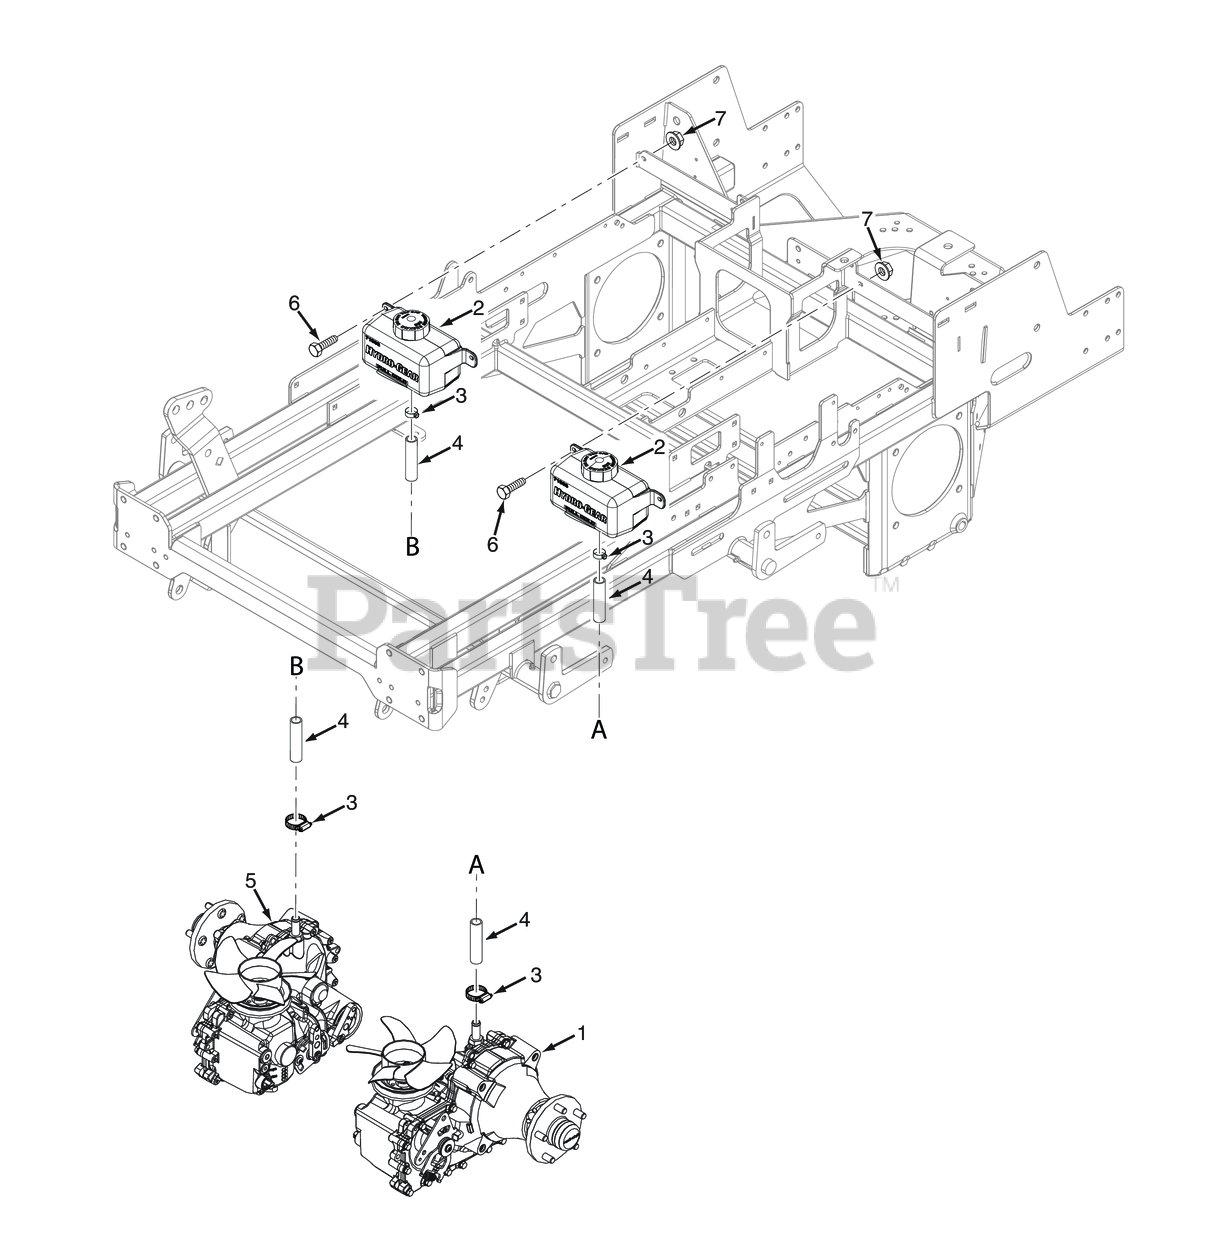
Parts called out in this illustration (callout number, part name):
1	Transaxle, LH
2	Hydraulic Tank, 1,000 ml
3	Clamp, 1" Max Dia.
4	HOSE 5/8 ID PUSH ON RUBBER CVD
5	Transaxle, RH
6	BOLT, HEX HEAD, 1/4-20 X 3/4 GR.5
7	NUT, 1/4-20 SERRATED FLANGE HEX HEAD
